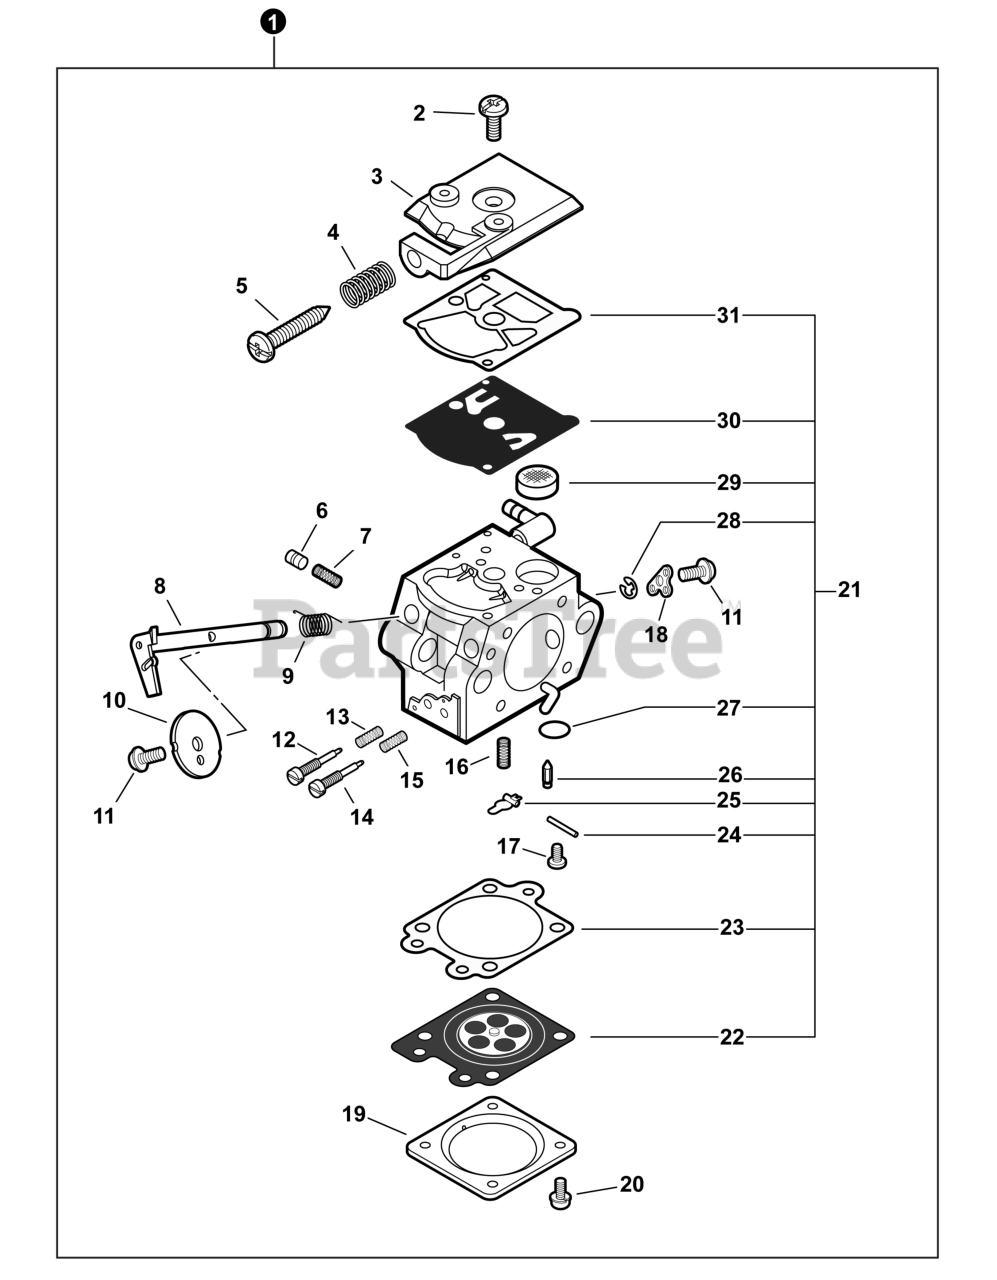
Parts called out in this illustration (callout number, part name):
1	CARBURETOR - WT-1109
3	COVER, FUEL PUMP
4	SPRING, IDLE ADJUST
5	SCREW, IDLE ADJUST
6	PISTON ASSY
7	SPRING, START VALVE
8	SHAFT, THROTTLE
9	SPRING, THROTTLE
10	VALVE, THROTTLE
12	NEEDLE, LOW SPEED
13	SPRING, NEEDLE
14	NEEDLE, HIGH SPEED
15	SPRING, HIGH NEEDLE
16	SPRING, METERING LEVER
18	LEVER, THROTTLE
19	COVER, METERING DIAPHRAGM
21	REPAIR KIT
22	DIAPHRAGM, METERING
23	GASKET, METERING DIAPHRAGM
24	PIN, METERING LEVER
25	LEVER, METERING
26	VALVE, INLET NEEDLE
27	PLUG, WELCH
29	SCREEN, FUEL INLET
30	DIAPHRAGM, PUMP
31	GASKET, FUEL PUMP
